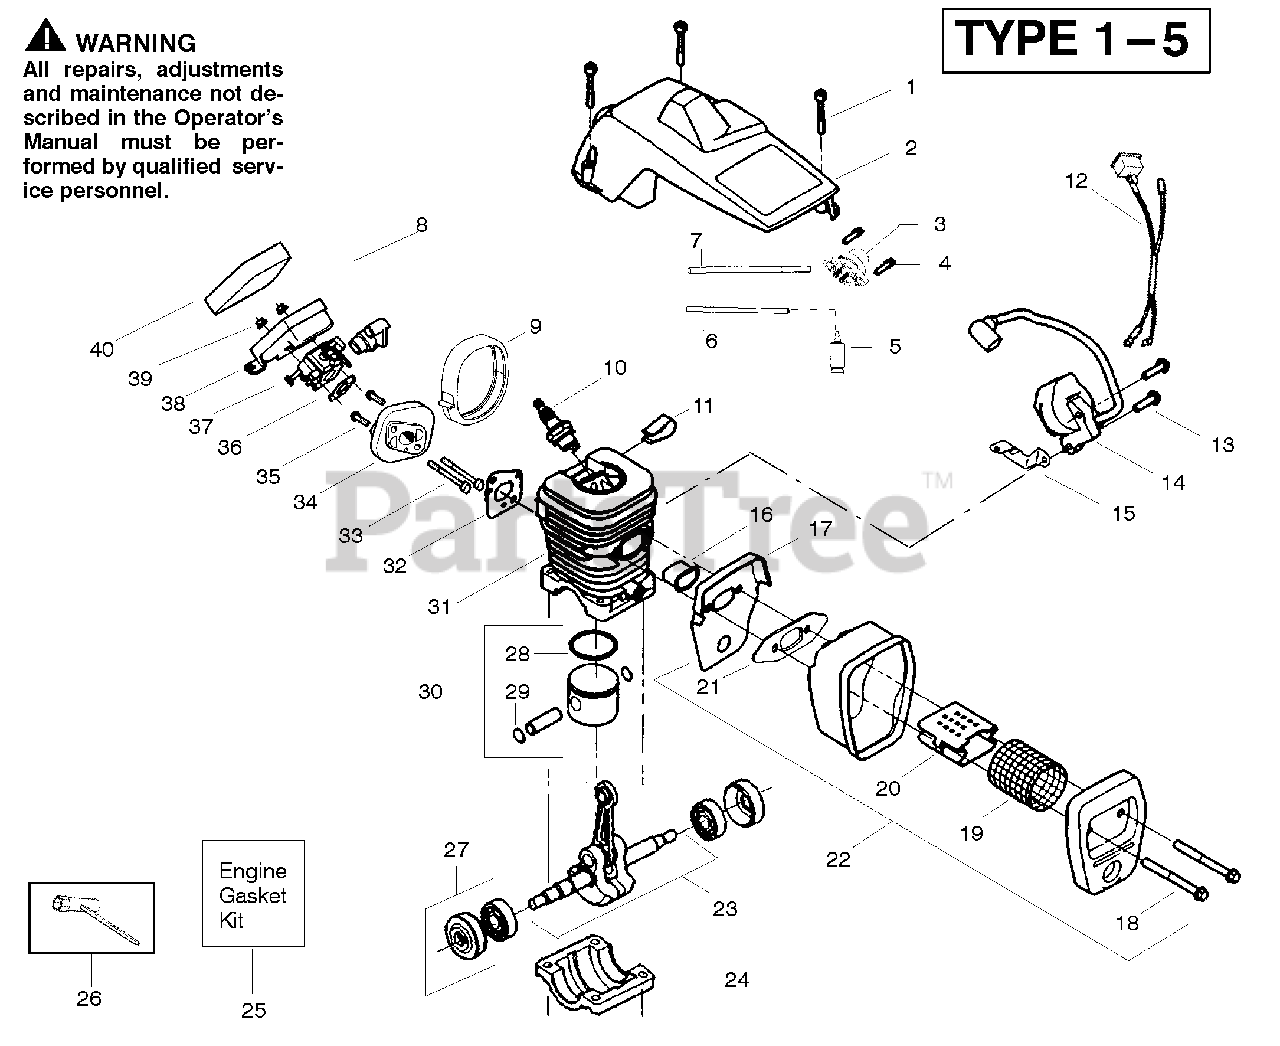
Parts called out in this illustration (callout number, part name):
2	Shield-Cylinder
3	Assy-Air Purge
5	Assy-Fuel Pick-up
6	Kit-Line Purge/Carb. (Small Dia)
7	Kit-Line Purge/Tank (large line)
8	Grommet-Carb Adjust.
9	Seal-Carb Adapter
10	Spark Plug (RCJ-7Y)
11	Clip-High Tension Lead
12	Assy-Wire Harness
14	Module-Ignition
16	Insulator-Heat
17	Back Plate-Muffler
20	Diffuser-Muffler
21	Gasket-Muffler
22	Assy-Muffler
23	Assy-Crankshaft 2250
23	Assy-Crankshaft 2450/2550
24	Cap-Crankcase
25	Kit-Engine Gasket
27	Assy-Seal & Bearing
28	Ring-Piston 2250
28	Ring-Piston 2450/2550
29	Retainer-Piston Pin
30	Kit-Piston 2250
30	Kit-Piston 2450/2550
31	Kit-Cylinder 2250
31	Kit-Cylinder 2450/2550
32	Gasket-Carb. Adapter
34	Kit-Carb. Adapter
35	Screw
37	Kit-Carburetor (WT-391)
37	Kit-Carburetor (WT-625)
38	Housing-Air Filter
40	Air Filter-Foam
